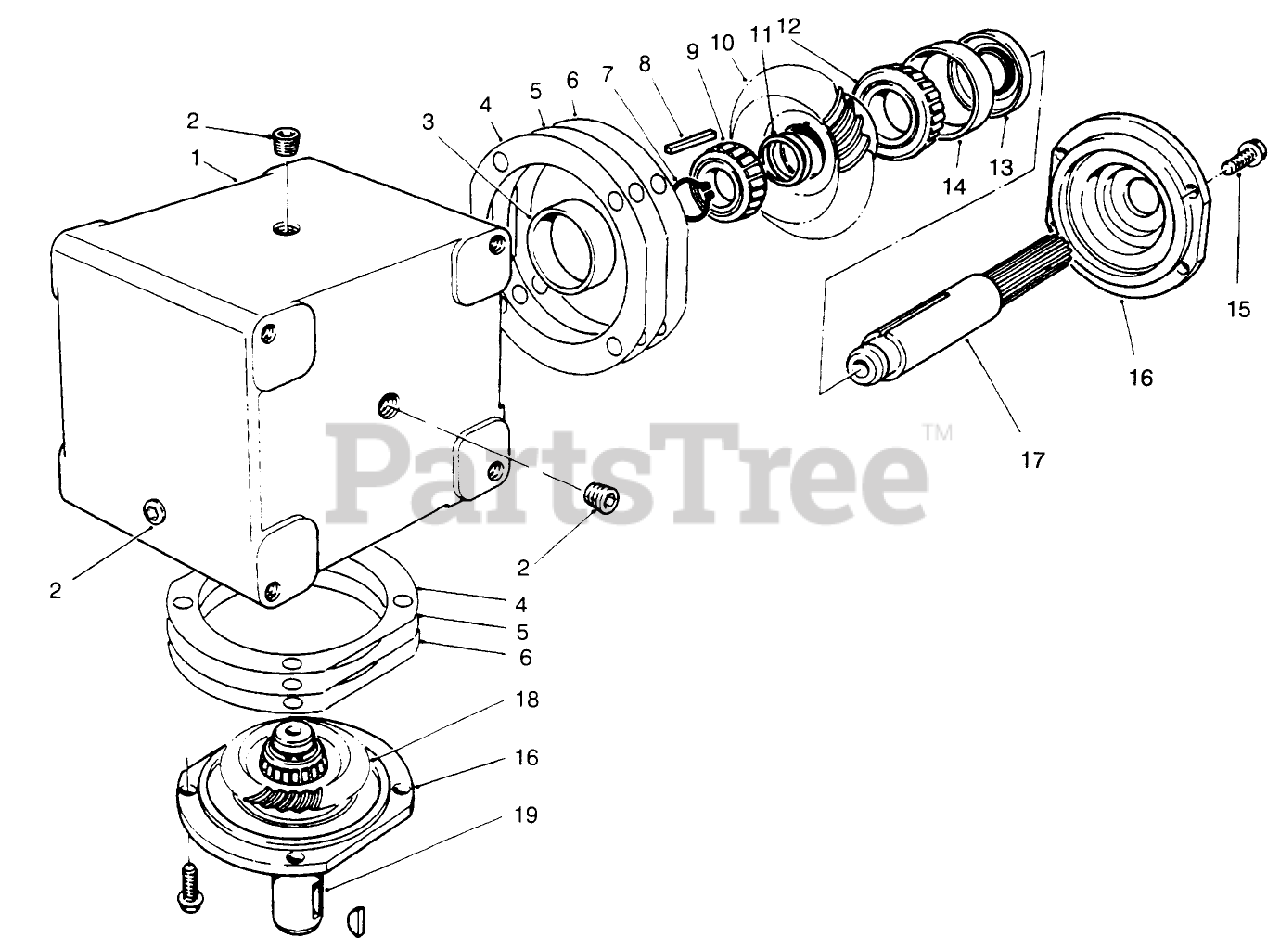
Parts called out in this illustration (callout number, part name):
1	HOUSING
2	PLUG (OBS, C/R TO 281-10)
3	Bearing Cup
4	GASKET
5	GASKET
6	GASKET
7	Ring-Retaining
8	Key
9	Cone
12	Cone
13	Seal
14	Cup
15	SCREW-HH (OBS, C/R TO 3234-5)
17	Shaft
19	Shaft
